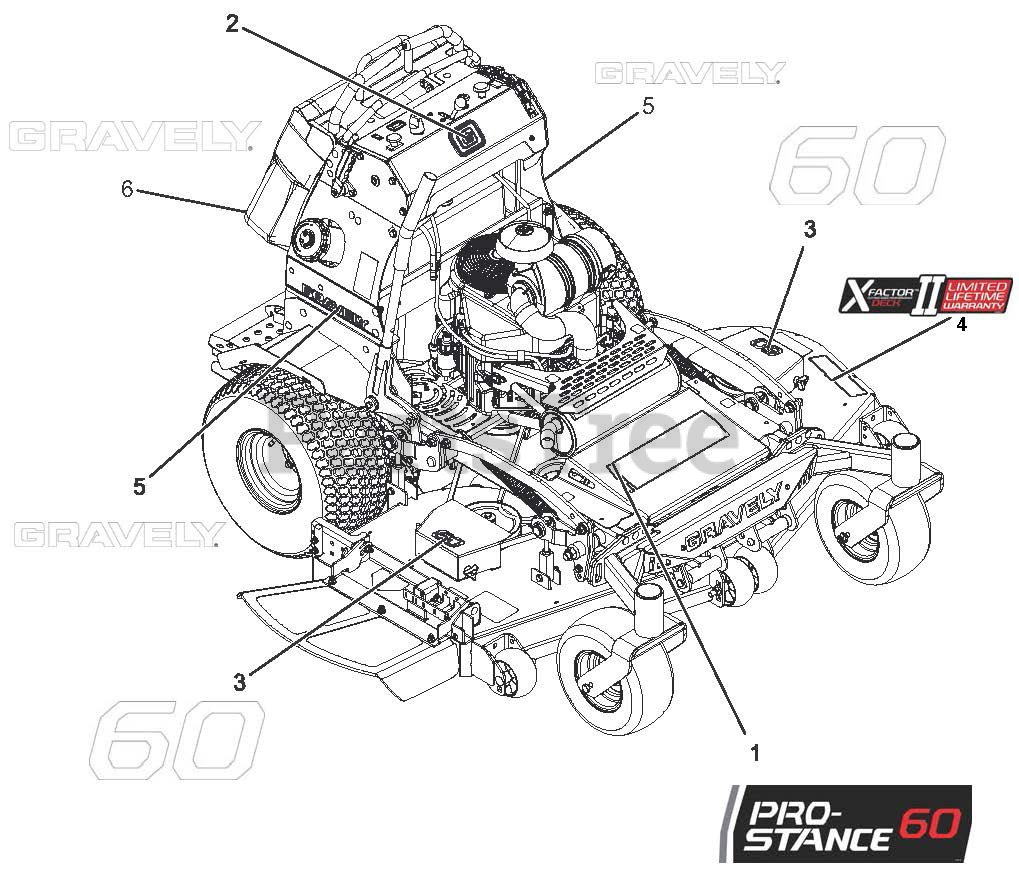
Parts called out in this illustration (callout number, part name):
1	DECAL, PROSTANCE 60
2	DECAL, GRAVELY BRAND
3	DECAL, 60"
4	DECAL, X-FACTOR DECK
5	DECAL, 9.5" GRAVELY LOGO
6	DECAL, 13.5" GRAVELY LOGO
